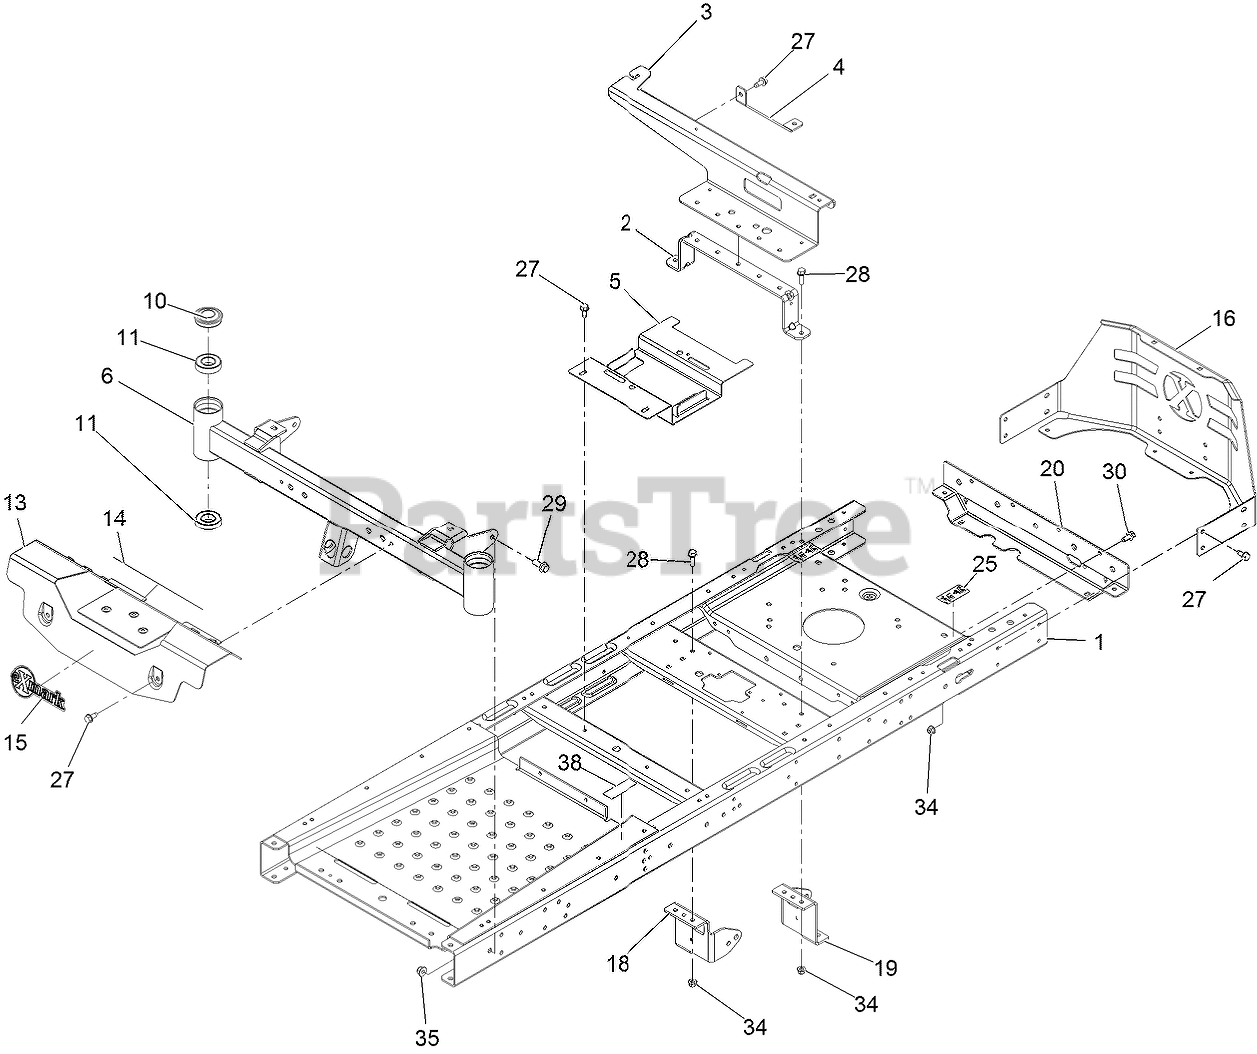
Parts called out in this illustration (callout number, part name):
1	FRAME ASM
2	BRACE-SEAT, REAR (NARROW)
3	SUPPORT-POD
4	SUPPORT-TANK, REAR
5	BRACKET-BATTERY
6	AXLE-FRONT, NARROW
10	Cap-Grease
11	BEARING-BALL
13	FOOTREST ASM
14	DECAL-WARNING
15	DECAL-EXMARK LOGO
16	GUARD-ENGINE, NARROW
18	MOUNT-HYDRO, FRONT (RIGHT
19	Mount-Hydro, Front (Left)
20	CROSSMEMBER-REAR, NARROW
25	DECAL-BYPASS
27	Screw-HWH 5/16-18 X 3/4 Tf
28	SCREW-HHF
29	SCREW-HHF 3/8-16 X 1
30	SCREW-HHF
34	NUT-HF, NI
35	NUT-HF, NI
38	DECAL-BRAKE, PARKING
